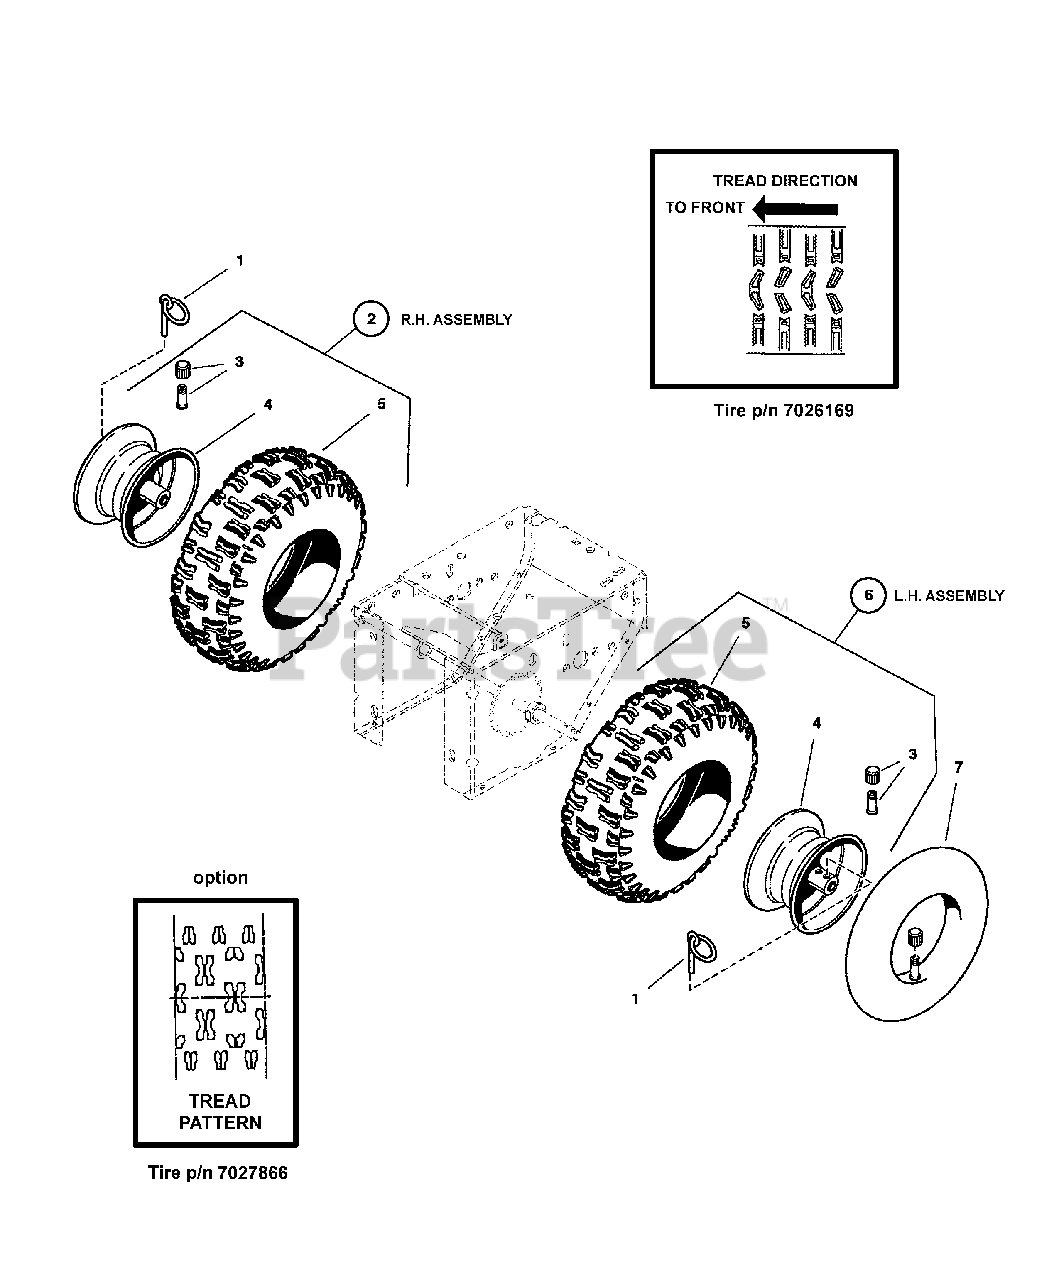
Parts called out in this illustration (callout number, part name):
1	KLIK- PIN, .310 ID x 1-3/4" Long
2	* ASSY, RH Tire and Wheel, 15 x 5.00-6 Carlisle X-Trac
3	VALVE STEM AND CAP
4	RIM, 6 x 3.25 (Weldment)
5	TIRE, 15 x 5.00-6, 2 Ply, Carlisle X-Trac
6	ASSY, LH Tire and Wheel, 15 x 5.00-6 Carlisle X-Trac
7	TUBE, Tire
